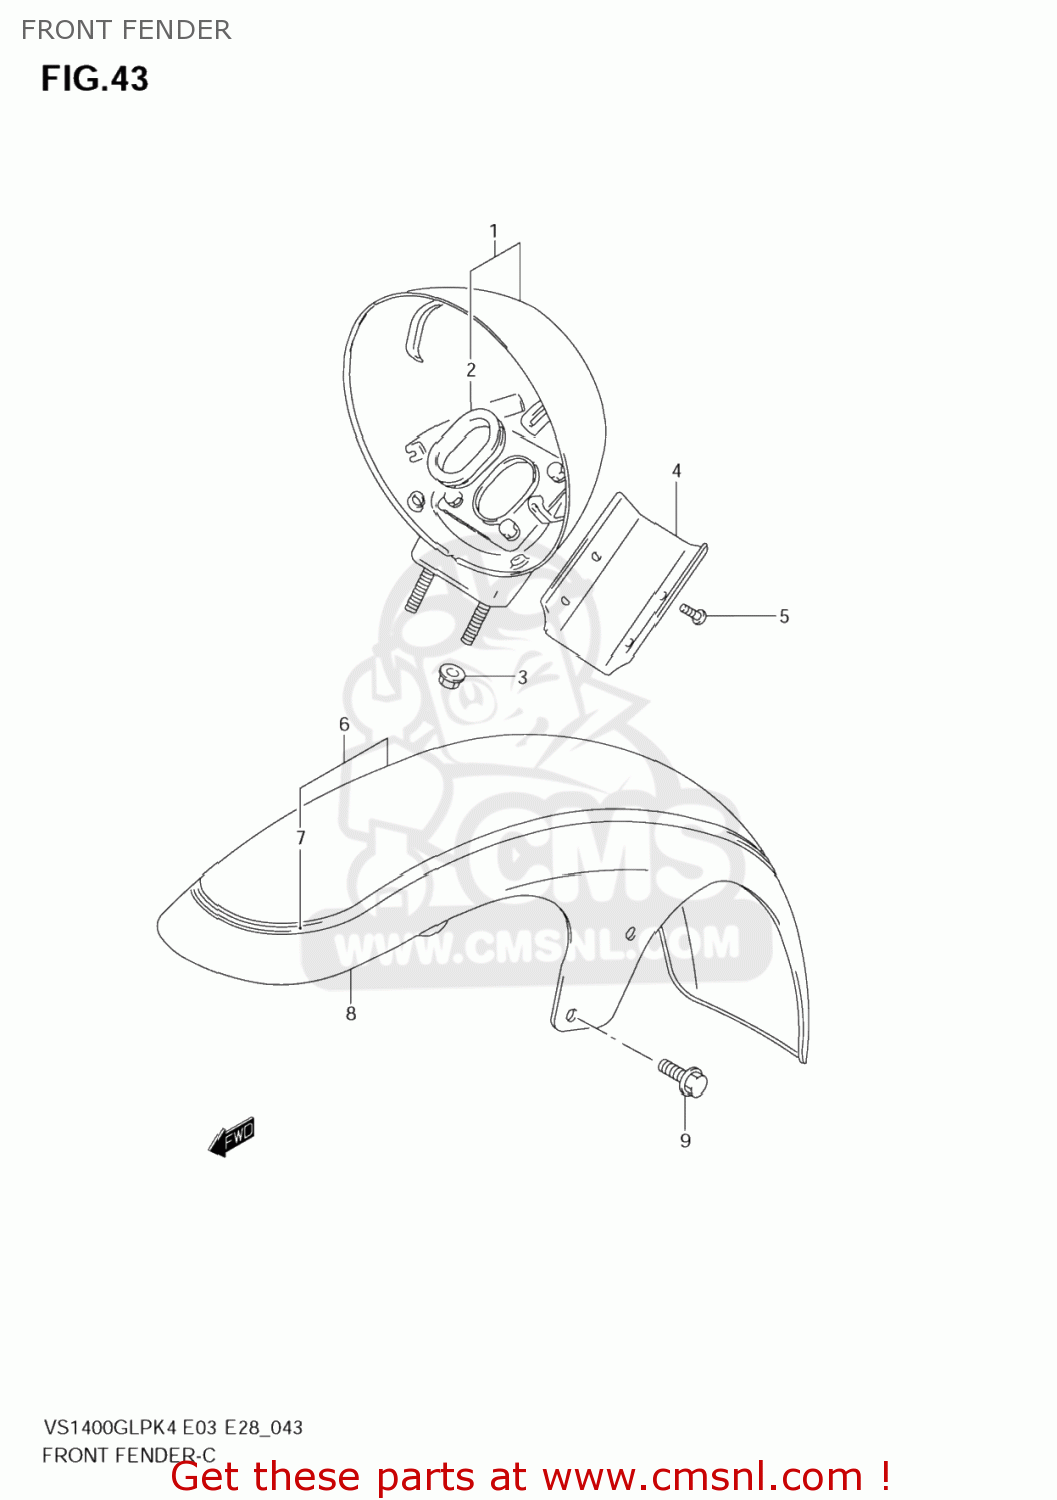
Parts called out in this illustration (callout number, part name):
1	HOUSING,HEADLAMP
2	GROMMET
3	NUT
4	COVER,HEADLAMP HSG
5	SCREW
6	FENDER ASSY,FR
7	TAPE,FR FENDER STRIPING
8	FENDER,FR
9	BOLT
